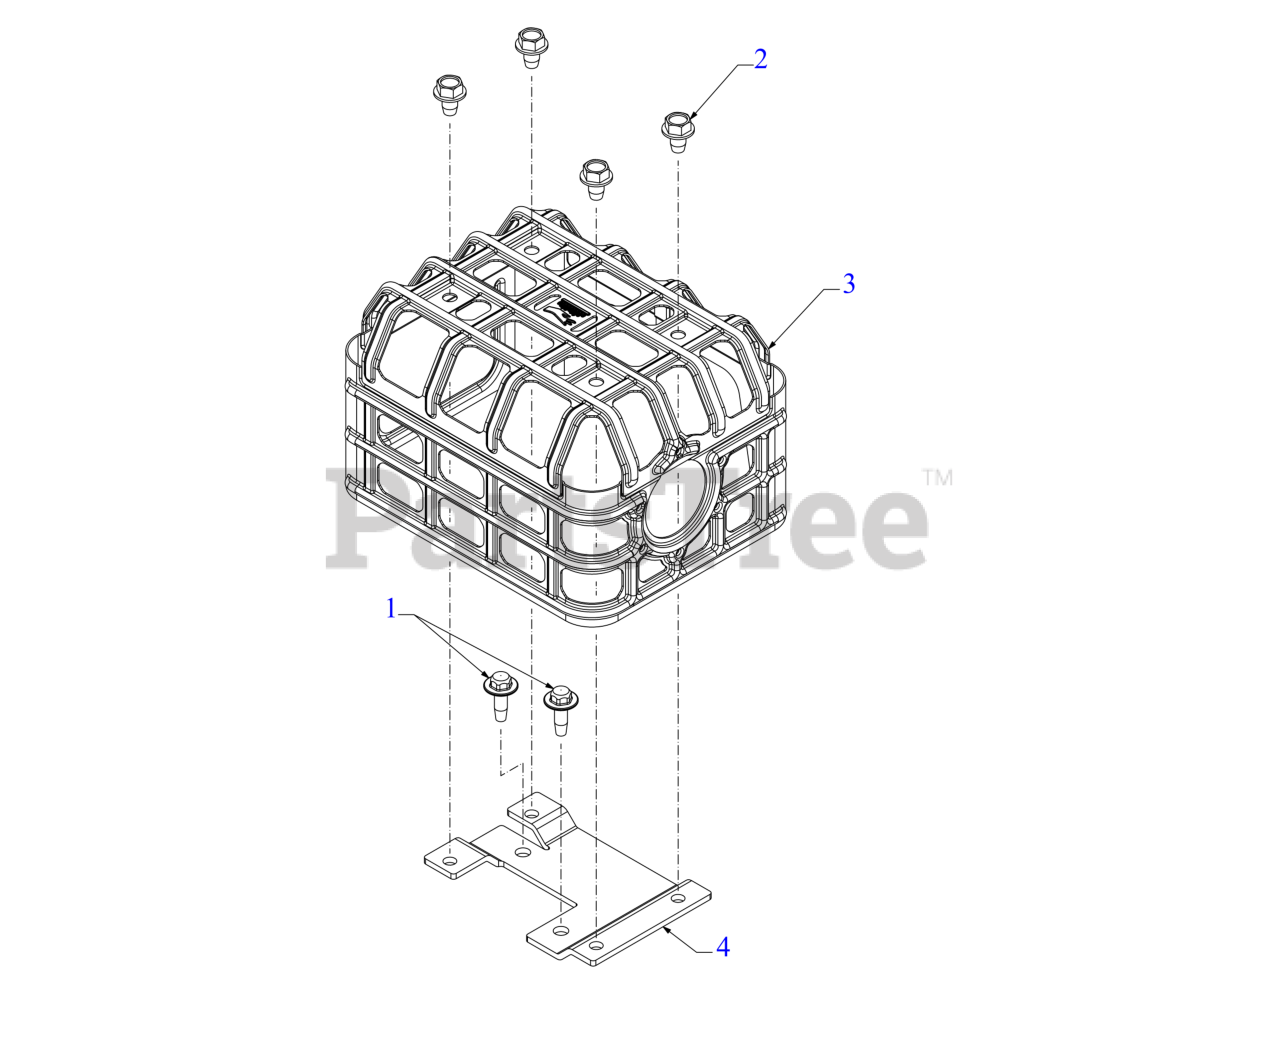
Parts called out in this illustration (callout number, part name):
1	SCREW M6-1 x .625
2	SCREW 1/4-20 x .375
3	STAMPED MUFFLER SHIELD
4	MUFFLER ADAPTER BRACKET (HONDA)
